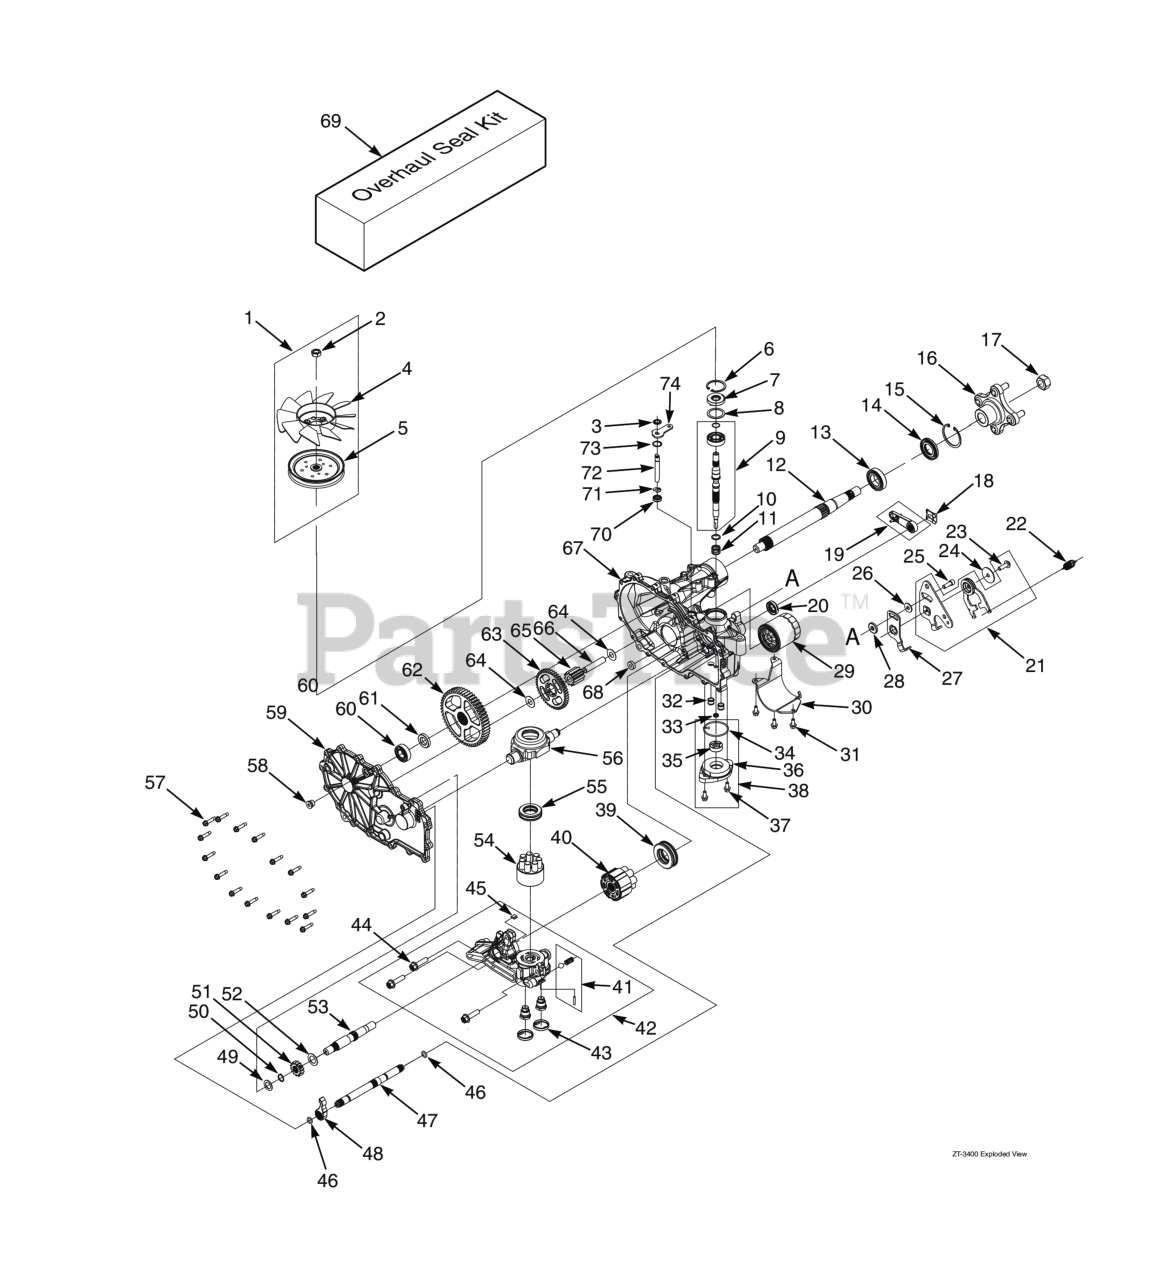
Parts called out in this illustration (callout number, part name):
1	Kit, Fan & Pulley
2	Fan Nut (order through Hydro-Gear)
3	Washer, OD Slotted .53 x 1.63 x .06
4	Fan, 7" (10 Blade)
5	Pulley"
6	Shaft, 2-Speed, Bevel
7	Seal, Lip 17 x 40 x 7
8	Washer, 1.23 x 1.56 x .04
9	Kit, Input Shaft
10	Washer, Flat .59 x .79 x .04
11	Spring, Block
12	Shaft, Axle
13	Bearing, Ball 1.0 x 52 x 15 Open
14	Seal, Lip 25 x 52 x 10 TC Gray
15	R i n g , Retaining 2.06 Internal
16	Hub, 4-Bolt
17	Nut, Hex Locking 3/4-16
18	Clip, Retaining
19	Lever, Brake (order through Hydro-Gear)
20	Seal, Lip 18 x 32 x 7
21	Kit, RTN Bi-Directional (Left Side)
21	Kit, RTN Bi-Directional (Right Side)
22	Spring, Extension, RTN - 44lbs
23	Bolt, Hex Head Cap Screw 5/16-24 x 1" Patch
24	Washer, .343 x 1.5 x .062
25	Bolt, Hex Head Cap Screw 5/16-24 x 1" Patch
26	Washer, 7/16 x 7/8 OD x .06 HT
27	Arm, Neutral (Right Side)
27	Arm, Neutral (Left Side)
28	Spacer, .320 x 1.005 x .179
29	Filter, Oil
30	Guard, Filter (Right Side)
30	Guard, Filter (Left Side)
31	Screw, Hex Flange 1/4-20 x .625
32	Tibe, Connecting
33	Seal, Lip 8 x 12 x 3-VC
34	O-Ring, -137 x .103 x 2.050
35	Gerotor Assembly (1.9 cc)
36	Cover, Charge Pump
37	Screw, Hex Flange 1/4-20 x .625
38	Kit, Charge Pump
39	Thrust Ball Bearing Assembly
40	Kit, Motor Cylinder Block
41	Kit, Charge Relief
42	Kit, Center Section (Right Side)
42	Kit, Center Section (Left Side)
43	Seal, Plug 1.250 x .250
44	Screw, Hex Flange Head 3/8-16 x 1-1/2"
45	Plate, By-Pass
46	O-Ring, -111 x .103 x 424
47	Shaft, Brake
48	Pawl, Brake
49	Washer, HT .62 ID x 1.0 OD x .05 Thick
50	Ring, Retaining .625
51	Gear, 13T Steel
52	Washer, .72 x 1.16 x .04
53	Shaft, Motor
54	Assembly, Block 7 Piston
55	Bearing, Thrust
56	Trunnion, Swashplate
57	Bolt, Hex Head 1/4-20 x 1-1/8"
58	Straight Thread Plug
59	Kit, Cover (Right Side)
59	Kit, Cover (Left Side)
60	Bearing, Ball .75 x 40 x 12
61	Spacer, .750 x 1.320 x .257
62	Gear, 54T
63	Gear, 45T
64	Washer, .5 x 1.0 x .03
65	Gear, 14T Steel
66	Jackshaft Pin
67	Kit, Housing Main (Right Side)
67	Kit, Housing Main (Left Side)
68	Magnet, Ring
69	Seal Kit
70	Seal, Lip .375 x .75 x .25
71	Ring, .Retaining .375 External
72	Rod, By-Pass
73	Ring, Retaining .750 Internal
74	Arm, By-Pass
75	Ring, Retainging .375 External
